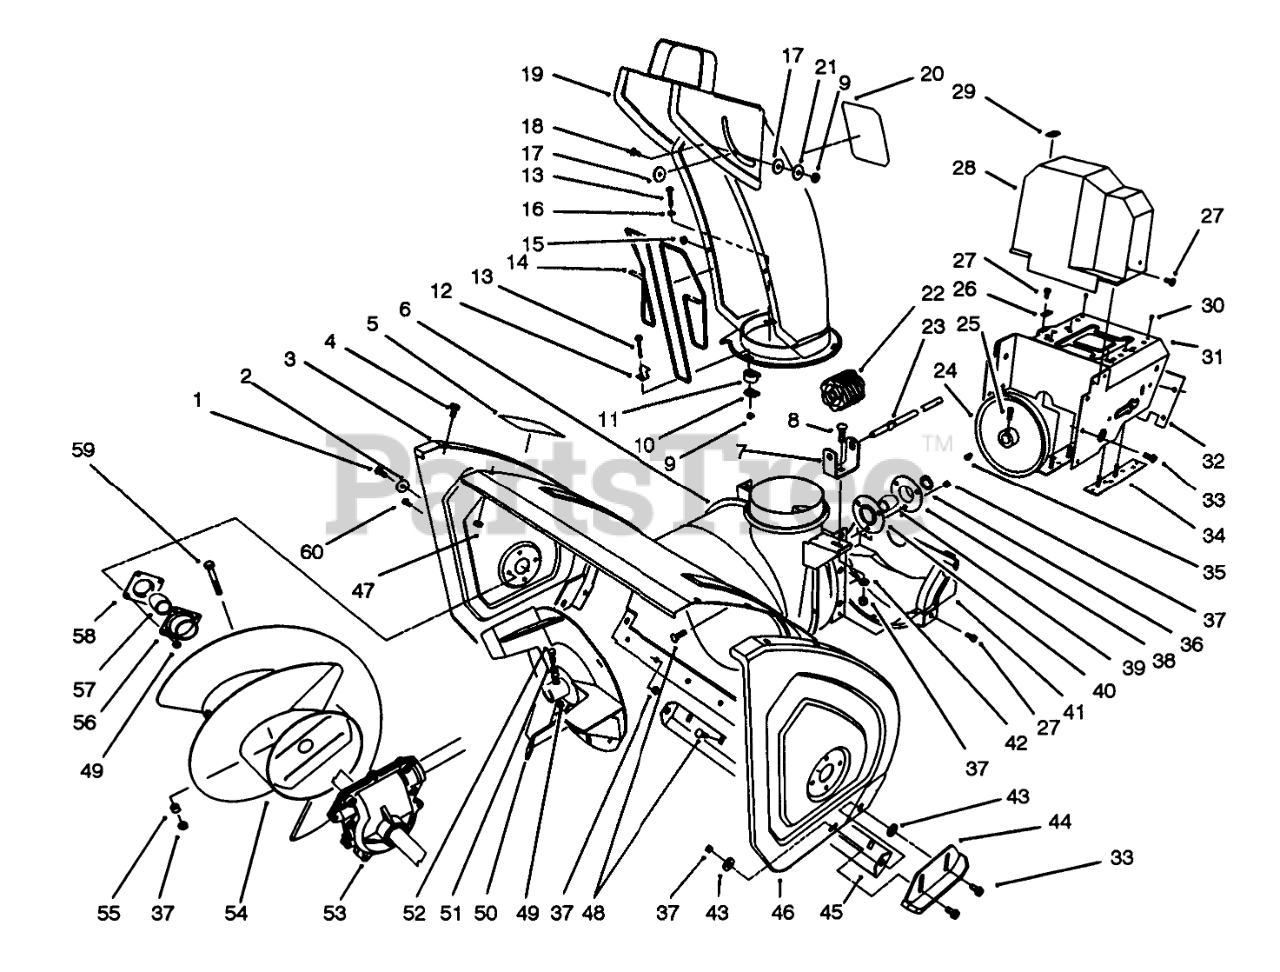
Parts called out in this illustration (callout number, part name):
1	SCREW-HH
2	WASHER
3	Plate-Side
4	SCREW-HHF
5	DECAL-WARNING, AUGER
6	Housing-24"
7	BRACKET-WORM, CHUTE
8	BOLT-CARR
9	NUT-LOCK, NI
10	PLATE-RETAINER, CHUTE
11	RETAINER-CHUTE
12	CLIP-GUARD, CHUTE
13	SCREW-HSH
14	GUARD-CHUTE
15	NUT-PUSH
16	WASHER-FLAT
17	WASHER-PLASTIC
19	Assembly
20	Decal-Danger
21	WASHER-FLAT
22	GEAR-WORM
23	ROD-CHUTE, LOWER
24	PULLEY-IMPELLER
25	SCREW-SET, SQH
26	RETAINER-CABLE
27	SCREW-HWH
28	COVER-BELT, UPPER
29	COVER-CABLE
30	RIVET-POP
31	Frame-Engine
32	Cover-Frame, Engine
33	SCREW-HHF
34	LH FRAME PLATE ASM
35	KEY-WOODRUFF
36	WASHER-THRUST
37	NUT-LOCK, NI
38	Flange-Bearing (Rear)
39	BEARING-BALL
40	Flange-Bearing (Front)
41	COVER-BELT, LOWER
42	WASHER-PLAIN
43	WASHER
44	Skid
45	Blade-Scraper
46	Plate-Side
47	NUT-LOCK, NI
48	SCREW-CARR
49	NUT-LOCK, NI
50	Impeller
51	SPACER
52	SCREW-HHF
53	AUGER GEARCASE ASM
54	Auger-R.H.
55	SPACER-HUB, AUGER
56	BEARING-FLANGE, FRONT
57	BEARING
58	BEARING-FLANGE, REAR
59	Auger Bolt
60	SCREW-HH
